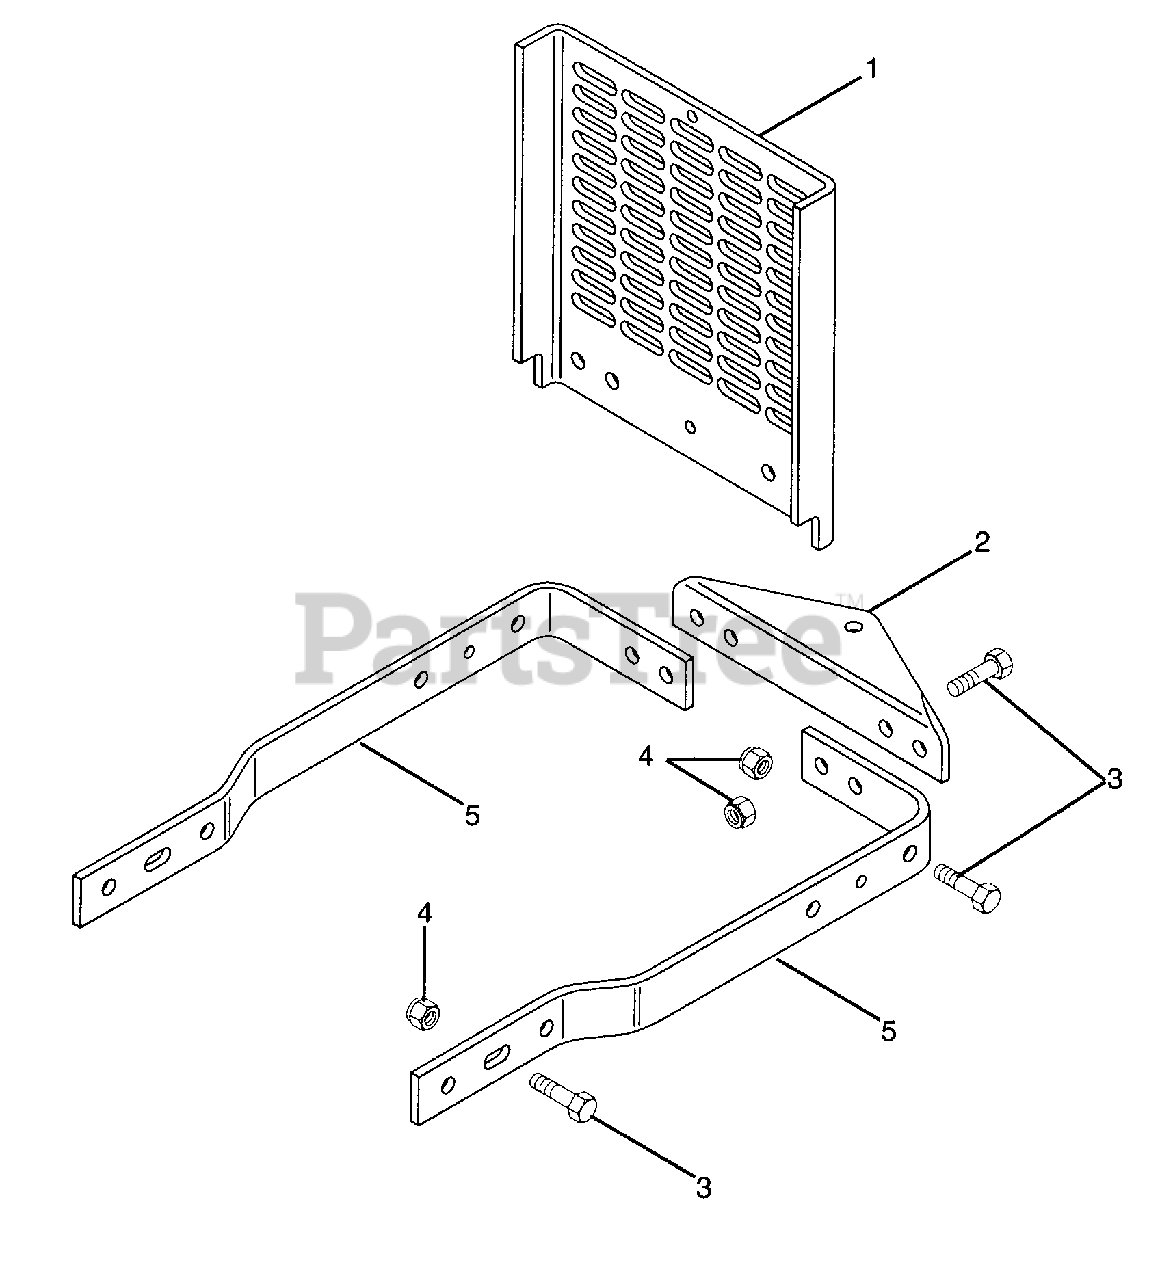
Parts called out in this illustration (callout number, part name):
1	Guard-Engine
2	Plate-Hitch
3	Bolt-Hex .50-13 x 1.75
4	Nut-Locking-Center .50-13 Grade 5
5	Arm-Rear Hitch
